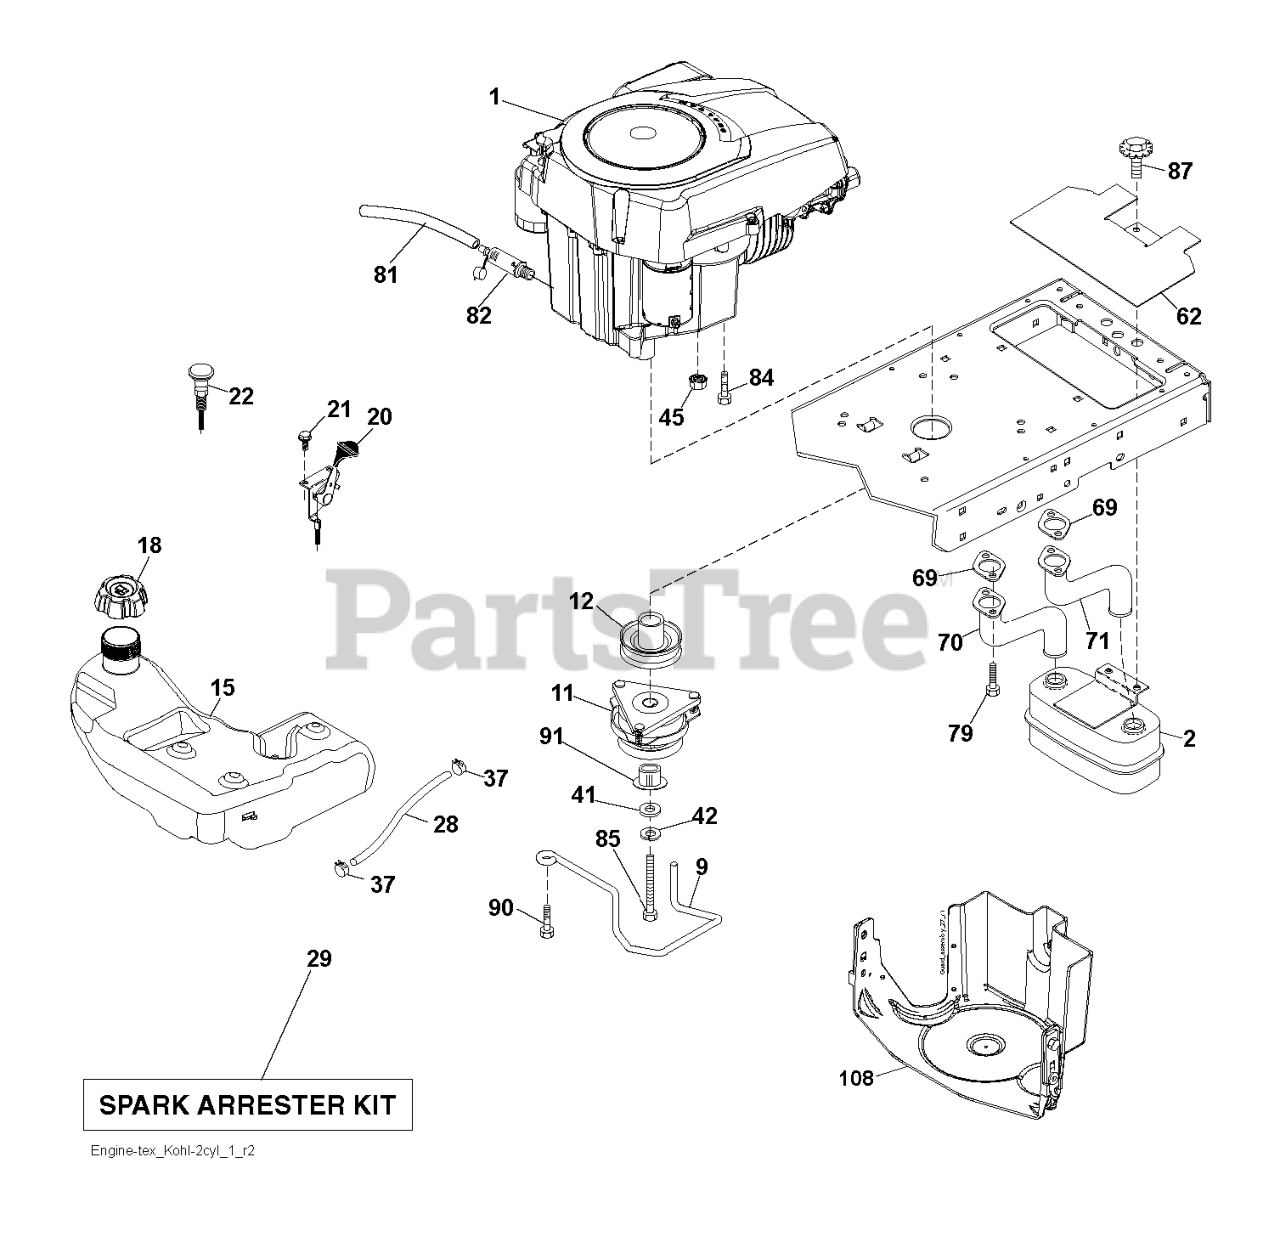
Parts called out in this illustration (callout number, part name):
2	MUFFLER.TWIN.CYL.LOW.TONE
9	KEEPER.BELT.ENGINE.4.2
11	CLUTCH MZ ZTR GT.48/54"1.125"
12	PULLEY ENGINE
15	TANK.FUEL.4GAL
18	RP CAP FUEL
20	THROTTLE CONTROL
21	SCREW.#10 X 0.750.BOS
22	CONTROL.CHOKE.ERGO.PUSH-IN.BLA
28	REPL BY 532 00 85-43
29	KIT.SPARK ARRESTOR 794945 B&S
37	HOSE CLAMP
42	LOCKWASHER
45	NUT
62	SHIELD.HEAT.MUFFLER
69	GASKET.EXHAUST.KOHL.CV18-CV26
70	RP.PIPE-EXHAUST LH
71	RP.PIPE-EXHAUST RH
79	SCREW.SOCKET HD.5/16-1
81	TUBE, DRAIN OIL ASM.
82	VALUE.OIL.DRAIN
84	SCREW 3/8-16X1
85	BOLT HEX 7/16-20 X 3.75 GR. 5
87	BOLT.5/16-18UNCX3/4 W/SEMS.BLK
90	SCREW 3/8-16X1
91	BUSHING.1.375OD
